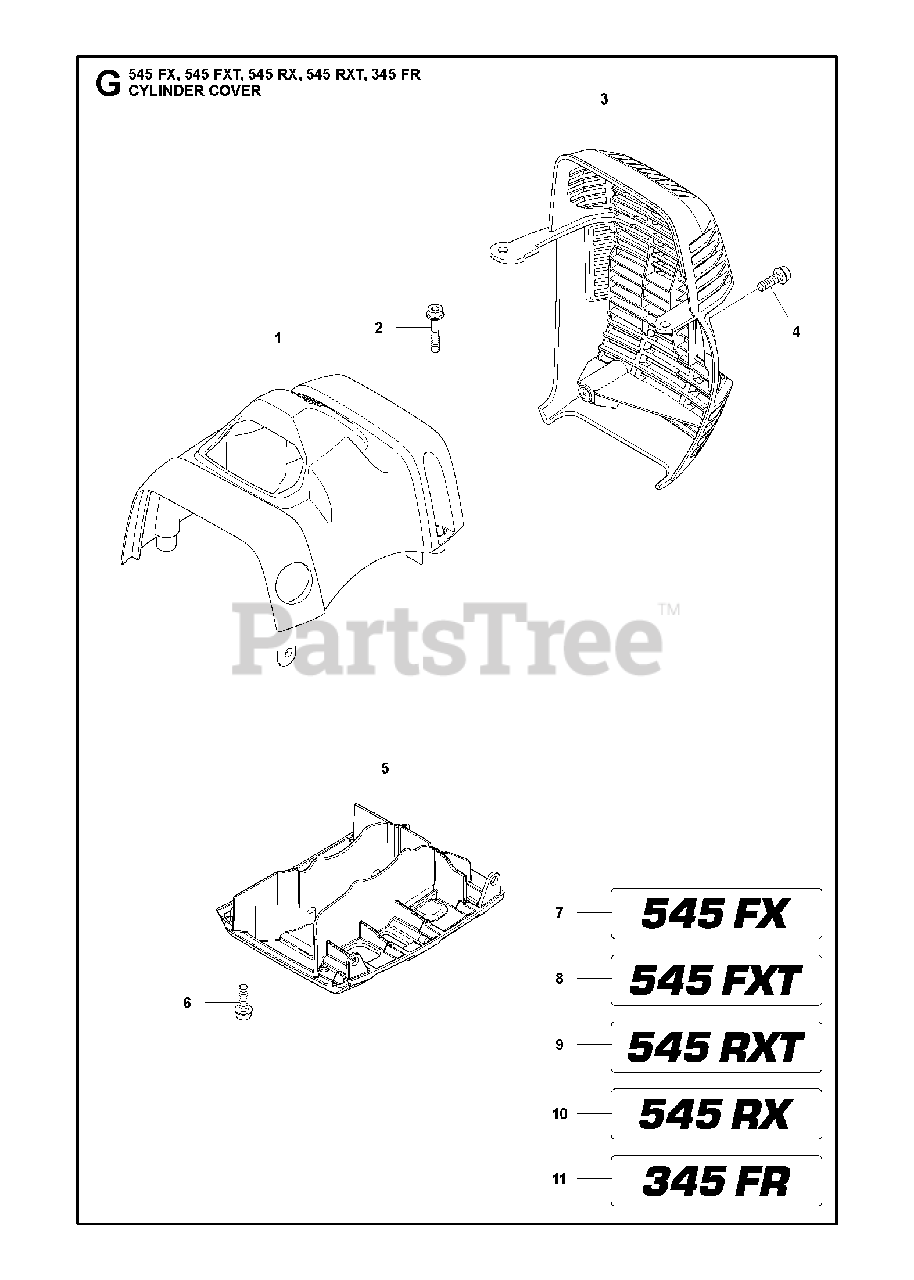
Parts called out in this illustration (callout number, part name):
1	CYLINDER COVER
2	SCREW IHSCFMO
3	HEAT PROTECTOR
4	SCREW IHSCFM
5	PROTECTIVE COVER
6	SCREW IHSCFM
7	LABEL
8	LABEL
9	LABEL
10	LABEL
11	LABEL
